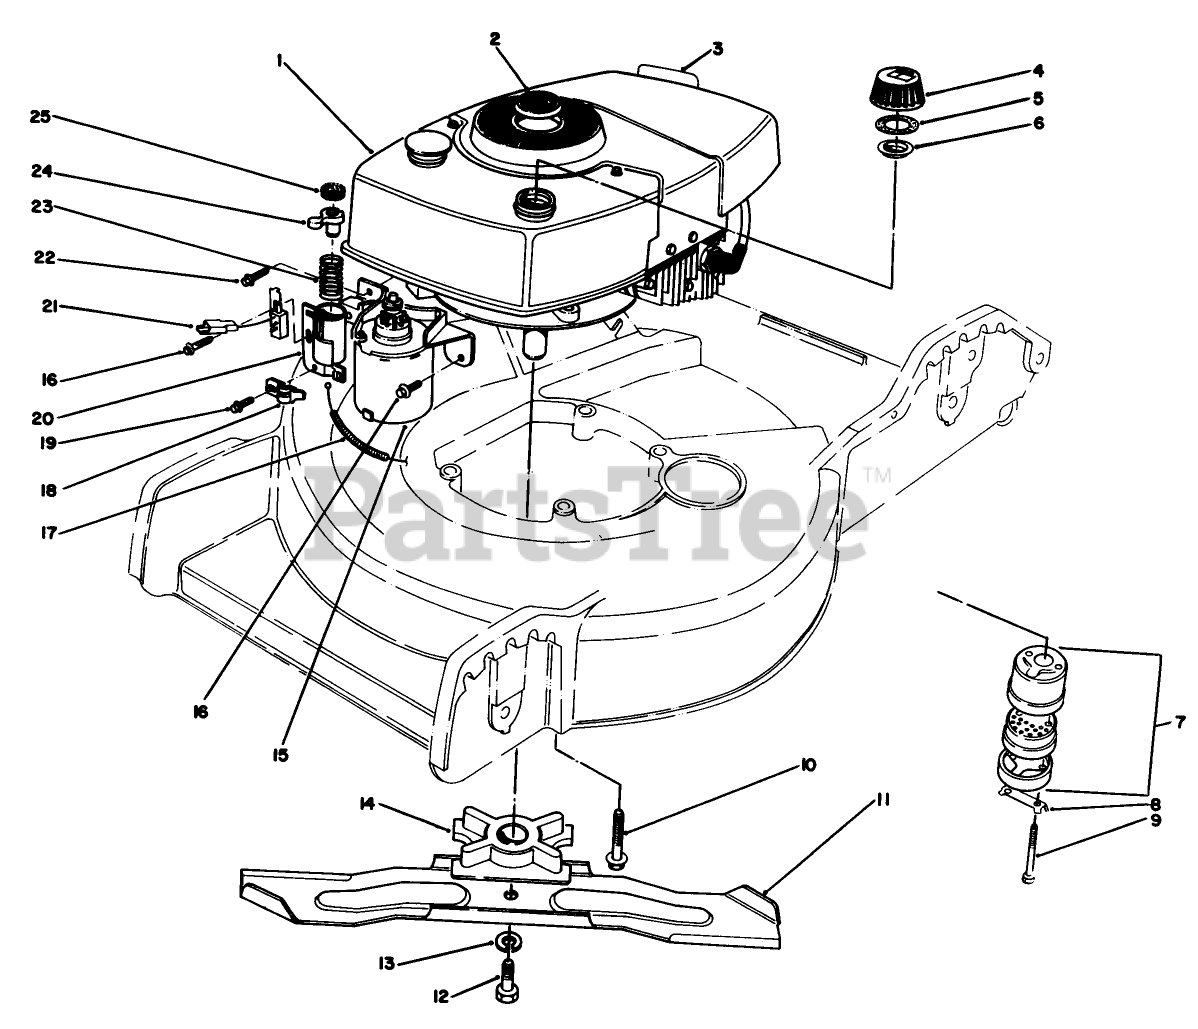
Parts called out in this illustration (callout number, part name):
1	Engine
2	PLUG BUTTON
5	GASKET
7	MUFFLER ASM
8	CLIP - LOCKING
9	SCREW-HH
10	3/8-16 X 2 CAPSCREW
13	WASHER-LOCK
14	BLADE RETAINER
16	SCREW
17	BRAKE CABLE-SUZUKI
19	SCREW
21	PUSH BUTTON SWITCH
24	Plunger
25	Pad-Friction
